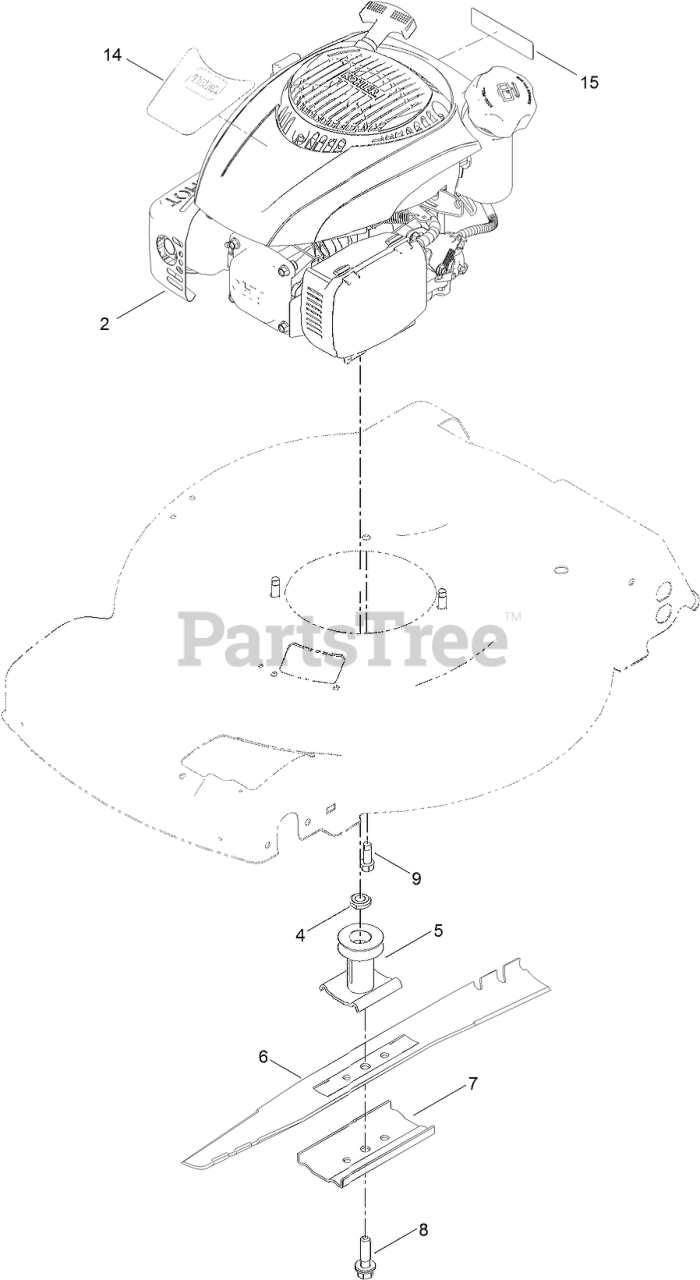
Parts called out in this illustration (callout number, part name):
4	SPACER-DRIVER
5	DRIVER-BLADE
6	BLADE-22 INCH
7	SUPPORT-BLADE
8	BOLT-BLADE
9	SCREW-TAPTITE
14	DECAL-SHROUD
15	DECAL-ARRESTOR, SPARK
